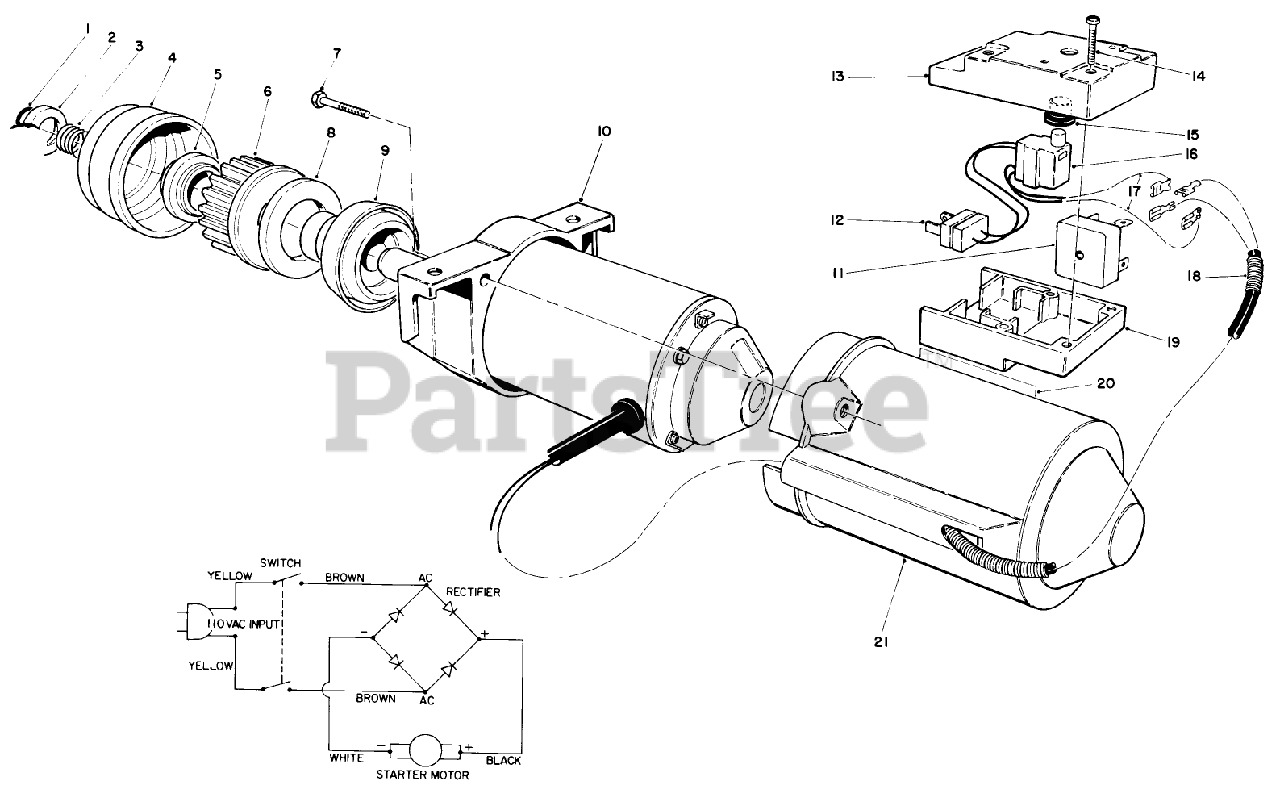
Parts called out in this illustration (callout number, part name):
1	RING-LOCK
2	PINION STOP
3	SPRING
4	ORDER BRIGGS 801293
5	ORDER BRIGGS 801293
6	Gear-Pinion
8	ORDER BRIGGS 801293
9	Drive-Pinion
11	RECTIFIER-BRIDGE
15	BOOT-SWITCH
16	SWITCH-STARTER
19	SWITCH BOX BASE
21	STARTER MOTOR COVER
